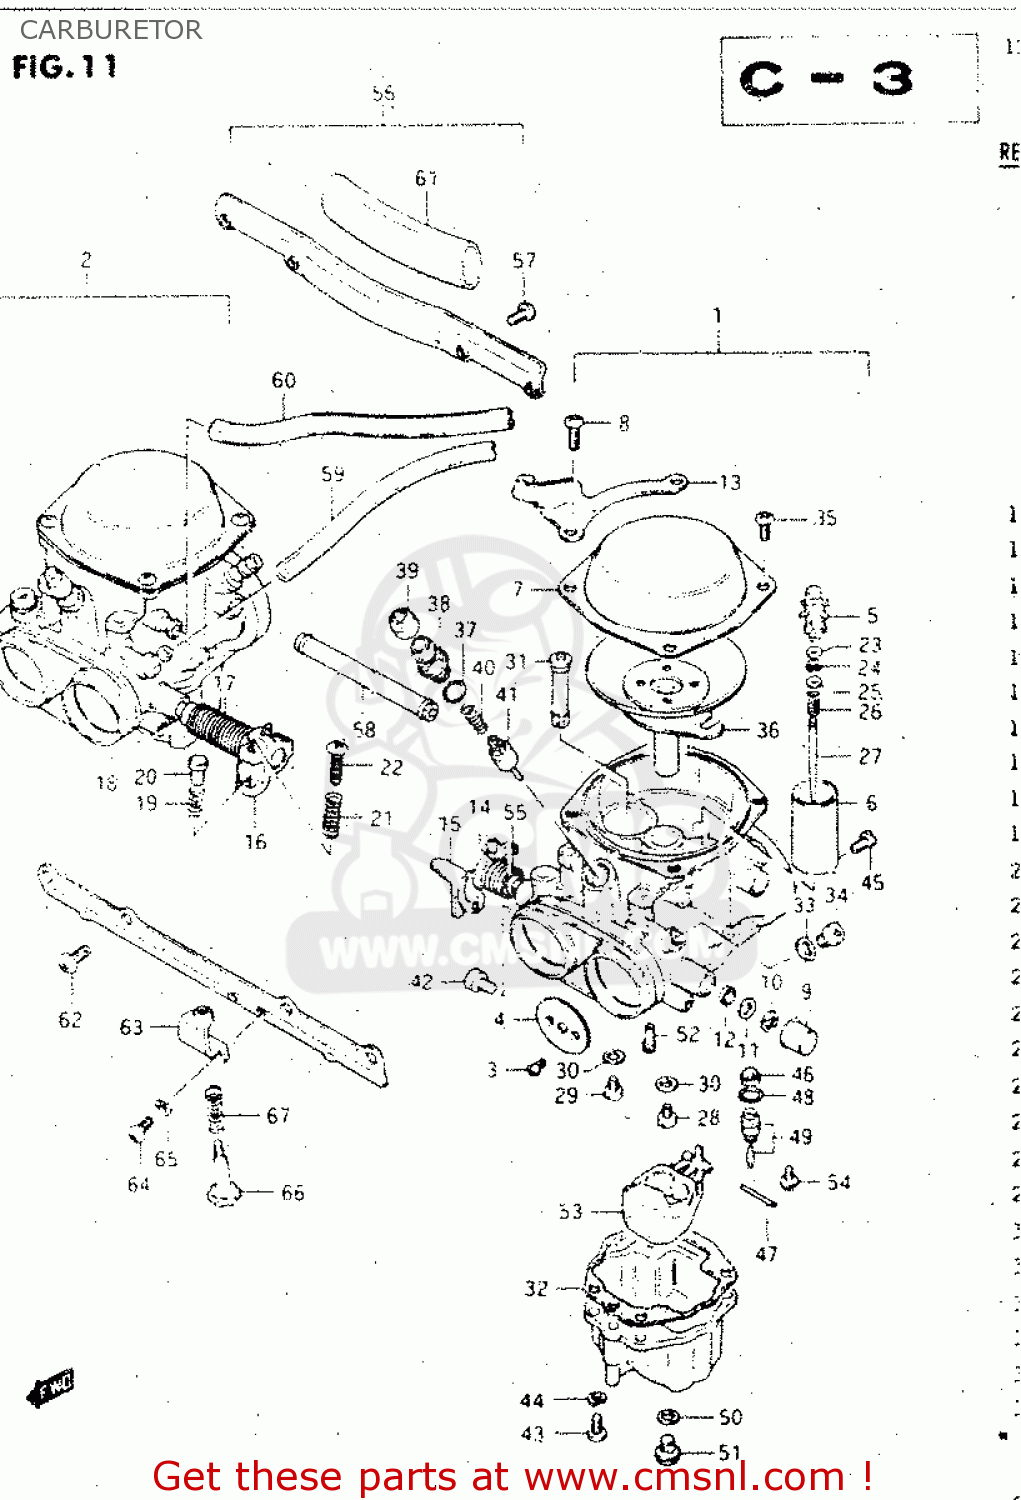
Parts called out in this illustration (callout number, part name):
1	CARBURETOR, LH
2	CARBURETOR, RH
3	SCREW
4	VALVE,THROTTLE
5	HOLDER,GUIDE
6	VALVE,THROTTLE
7	COVER,DIAPHRAGM
8	SCREW
9	CAP,THROTTLE SHAFT
10	E RING
11	GASKET,THROTTLE SHAFT (NAS)
12	SEAL
13	BRACKET,THROTTLE CABLE
14	SPRING,THROTTLE SHAFT
15	SHAFT ASSEMBLY
16	SHAFT ASSEMBLY
17	SPRING
18	RING
19	SPRING,THROTTLE SCREW
20	PIN,THROTTLE LEVER
21	SPRING
22	SCREW
23	RING
24	CAP,LEVER
25	WASHER
26	SPRING
27	NEEDLE, JET (5C13-3)
28	JET,MAIN(90)
29	JET,MAIN(97.5)
30	WASHER,NEEDLE NOZZLE
31	JET, NEEDLE (P-4)
32	GASKET,FLOAT CHAMBER (MCA)
33	WASHER
34	SCREW
35	SCREW
36	DIAPHRAGM,CARBURETOR
37	O RING
38	HOLDER,GUIDE
39	CAP
40	SPRING
41	VALVE,STARTER
42	SCREW
43	SCREW
44	WASHER,LOCK
45	JET, PILOT AIR (130)
46	FILTER
47	PIN,FLOAT
48	O-RING,NEEDLE VALVE
49	VALVE ASSEMBLY,NEEDLE
50	GASKET (NAS)
51	PLUG,DRAIN
52	JET,PILOT(37.5)
53	FLOAT
54	SCREW
55	RING,THROTTLE SHAFT
56	FLANGE ASSEMBLY,CARBURETOR
57	SCREW
58	PIPE,CARBURETOR
59	HOSE 4.5X8X390
60	HOSE
61	HOSE(16X19X100)
62	SCREW
63	BRACKET,SLOW ADJUST
64	SCREW
65	LOCK WASHER
66	ADJUSTER
67	SPRING
